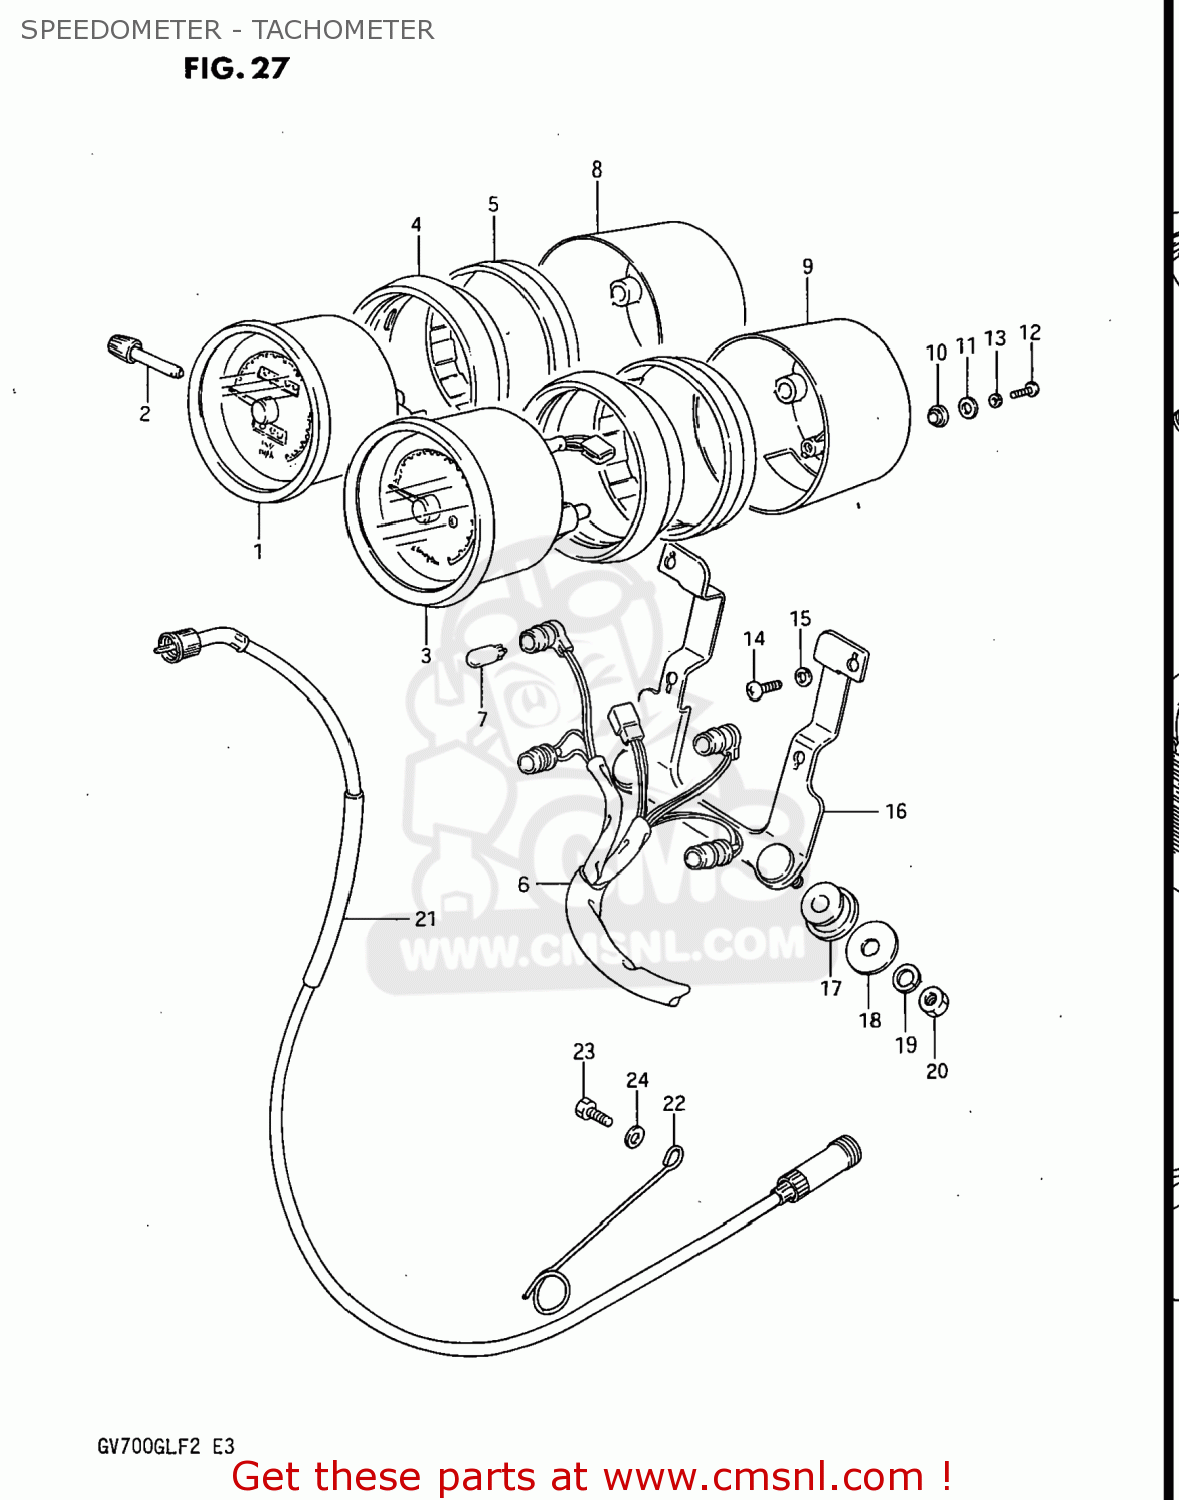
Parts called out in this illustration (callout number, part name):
1	SPEEDOMETER ASSEMBLY
2	KNOB
3	TACHOMETER
4	COVER,METER
5	CUSHION,METER
6	SOCKET,METER
7	BULB(12V3.4W,T10)
8	COVER,METER UNDER
9	COVER,TACHOMETER UNDER
10	CUSHION,METER
11	WASHER
12	SCREW 4X10
13	LOCK WASHER
14	SCREW 5X10
15	LOCK WASHER
16	BRACKET,METER
17	CUSHION,METER BRACKET
18	WASHER (8.5X20X1.6)
19	LOCK WASHER
20	NUT
21	CABLE ASSY,SPEEDOMETER
22	CLAMP,SPEEDOMETER CABLE
23	BOLT, UPPER
24	WASHER
